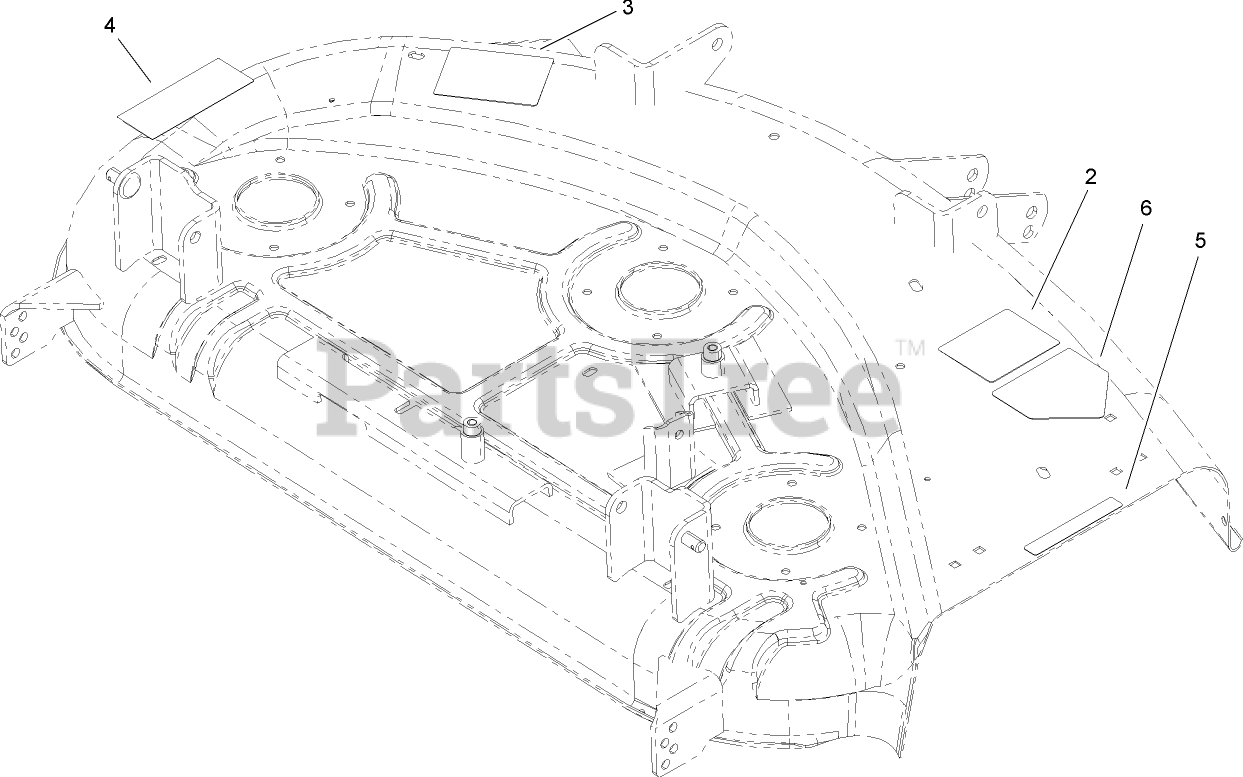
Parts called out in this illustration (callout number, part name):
2	DECAL-ROUTING, BELT
3	DECAL-WHEEL, GAGE
4	DECAL-DANGER
5	DECAL-CAUTION
6	DECAL-DANGER
